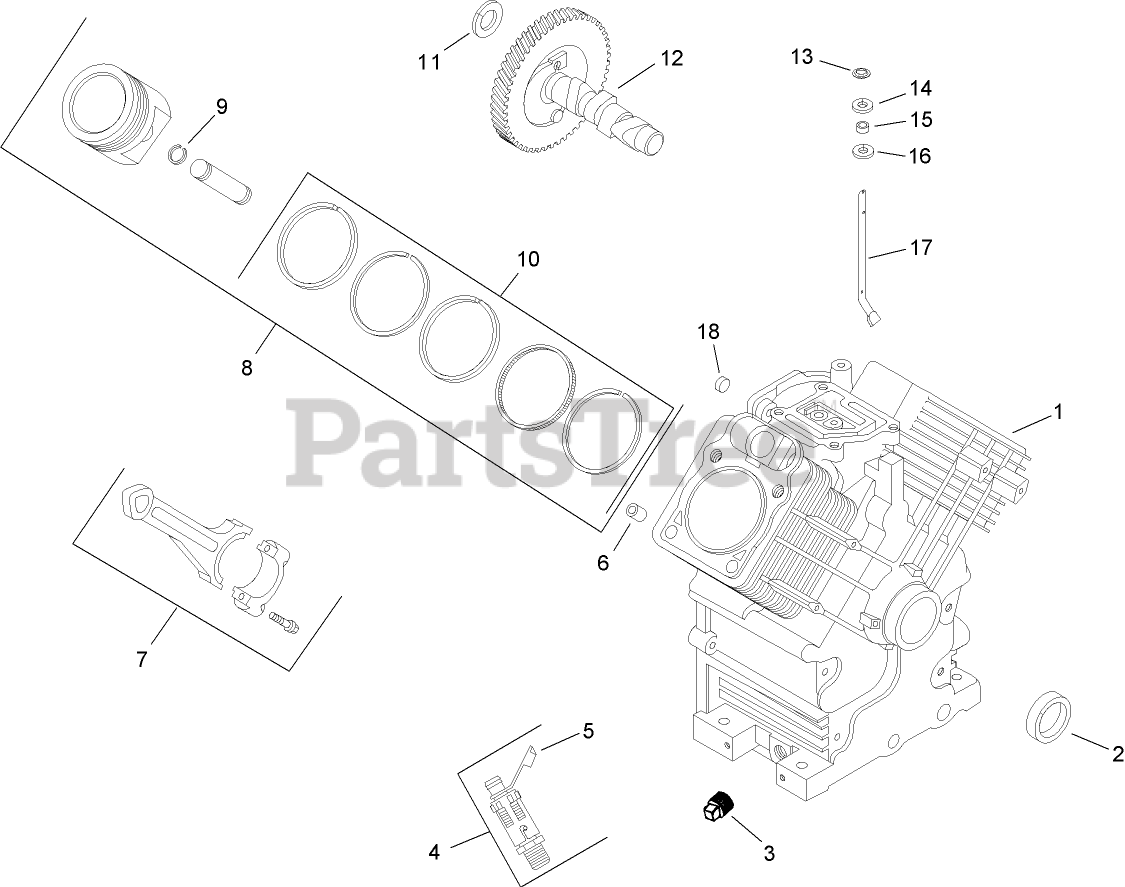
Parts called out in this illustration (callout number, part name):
2	SEAL-OIL
3	PLUG-PIPE, SQ HD (3/8)
4	OIL DRAIN VALVE KIT
5	CAP-VALVE, OIL DRAIN
6	PIN-LOCATING
7	Rod-Connecting (std)
7	Rod-Connecting (.25)
8	Piston and Ring Set (STD)
8	Piston and Ring Set (.08)
8	Piston and Ring Set (.25)
8	Piston and Ring Set (.50)
9	RETAINER-PIN, PISTON
10	Ring Set (.25)
10	Ring Set (.50)
11	SHIM-CAMSHAFT (YELLOW .034)
11	SHIM-CAMSHAFT (RED .032)
11	SHIM-CAMSHAFT (BLACK .04)
11	SHIM-CAMSHAFT (WHITE .028)
11	SHIM-CAMSHAFT (BLUE .03)
11	SHIM-CAMSHAFT (GREEN .036)
11	SHIM-CAMSHAFT (GRAY .038)
12	CAMSHAFT KIT
13	RETAINER-RING
14	WASHER-FLAT (9MM)
15	SEAL-CROSS SHAFT, GOVERNOR
16	WASHER-FLAT (11/32)
17	SHAFT-CROSS, GOVERNOR
18	PLUG-CUP
